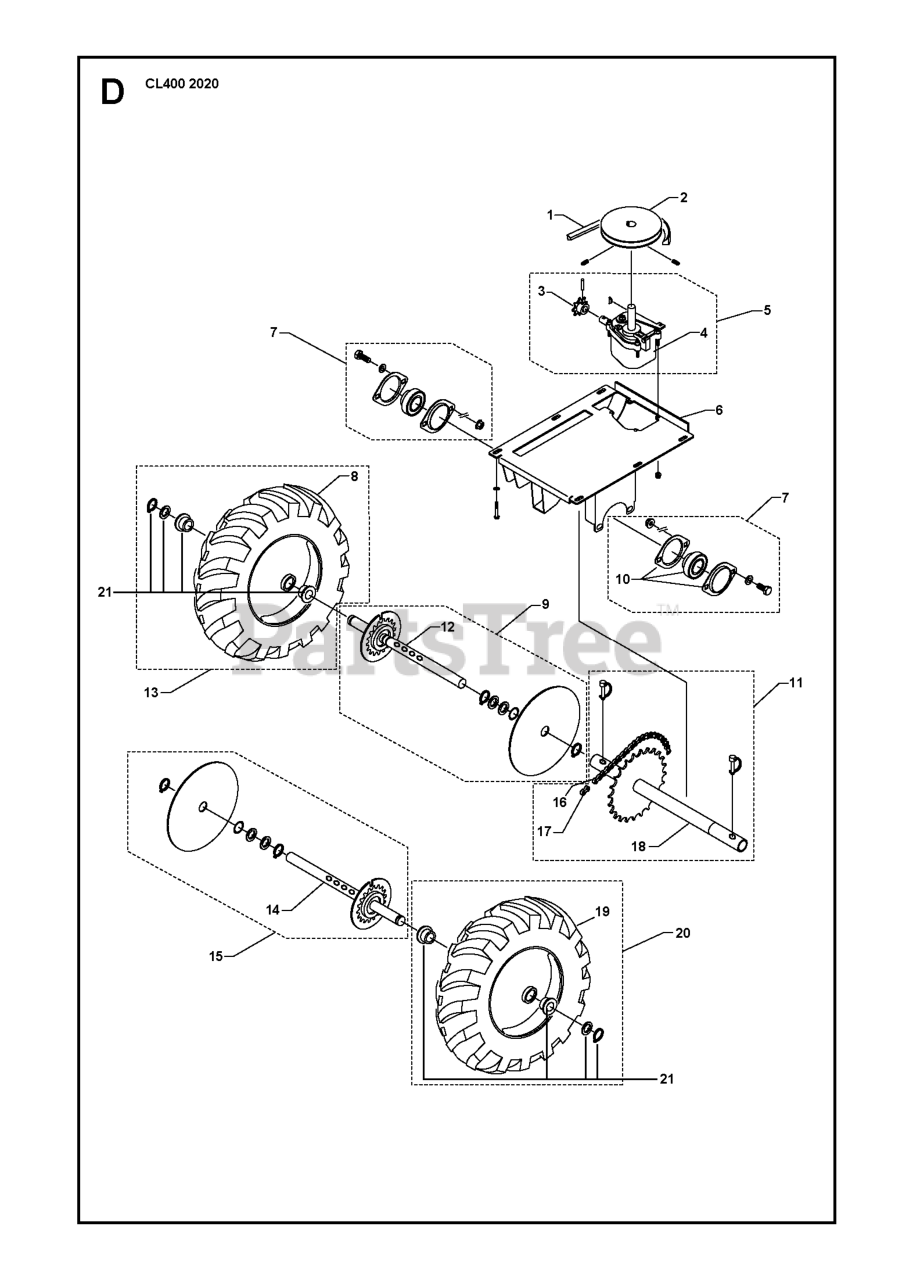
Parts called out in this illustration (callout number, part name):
4	Transmissions
7	Ball Bearings
12	Axles
14	Axles
16	Chain Catcher
21	BUSHNG KIT
